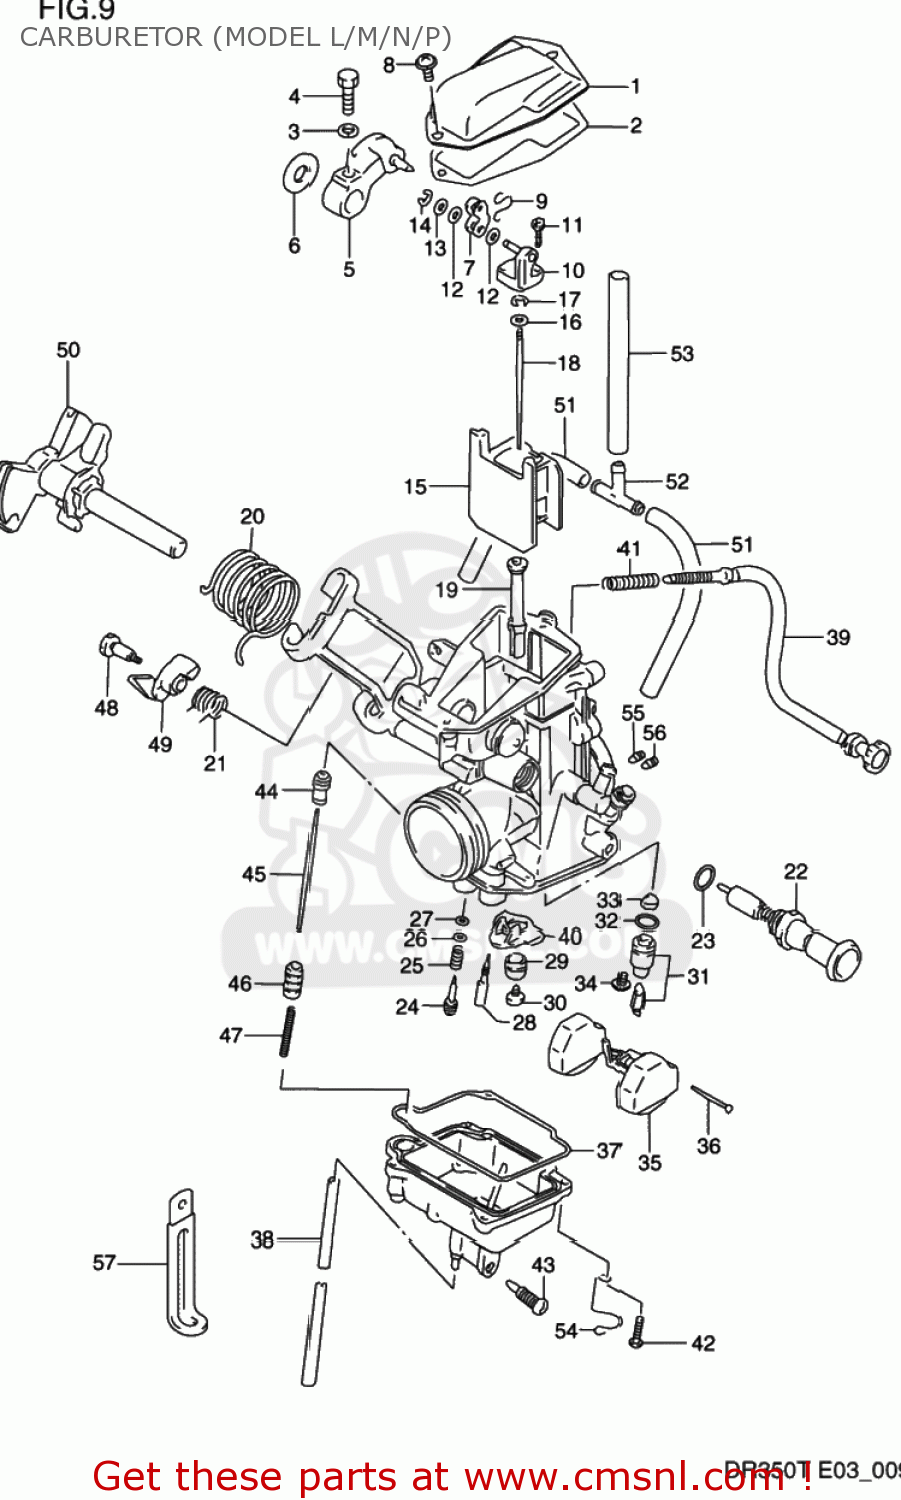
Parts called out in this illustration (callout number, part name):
1	COVER,CARBURETOR,TOP
2	GASKET,CARBURETOR TOP (NAS)
3	LOCK,WASHER
4	BOLT
5	ARM,THROTTLE
6	RING,THROTTLE SHAFT
7	PLATE
8	SCREW
9	SPRING
10	CONNECTOR
11	SCREW
12	GASKET (NAS)
13	WASHER
14	E-RING
15	VALVE,PISTON
16	WASHER,JET NEEDLE
17	CLIP
18	NEEDLE,JET
19	JET,NEEDLE(P-8)
20	SPRING
21	SPRING
22	PLUNGER ASSY
23	O RING
24	SCREW,PILOT
25	SPRING
26	WASHER
27	O RING,PILOT AIR SCREW
28	JET,PILOT(37.5)
29	RING,MAIN JET FIXING
30	JET,MAIN(132.5)
31	VALVE ASSEMBLY,NEEDLE
32	O-RING,NEEDLE VALVE
33	FILTER
34	SCREW
35	FLOAT
36	PIN,FLOAT
37	O RING,FLOAT CHAMBER
38	HOSE
39	ADJUSTER ASSY
40	RING
41	SPRING
42	SCREW
43	SCREW,DRAIN
44	BOOT, ACCELE PUMP ROD
45	ROD
46	PLUNGER
47	SPRING
48	BOLT
49	LEVER
50	SHAFT ASSEMBLY
51	HOSE
52	JOINT,3 WAY
53	HOSE
54	CLIP
55	JET,MAIN AIR(0.9)
56	JET,AIR(1.0)
57	CLAMP
